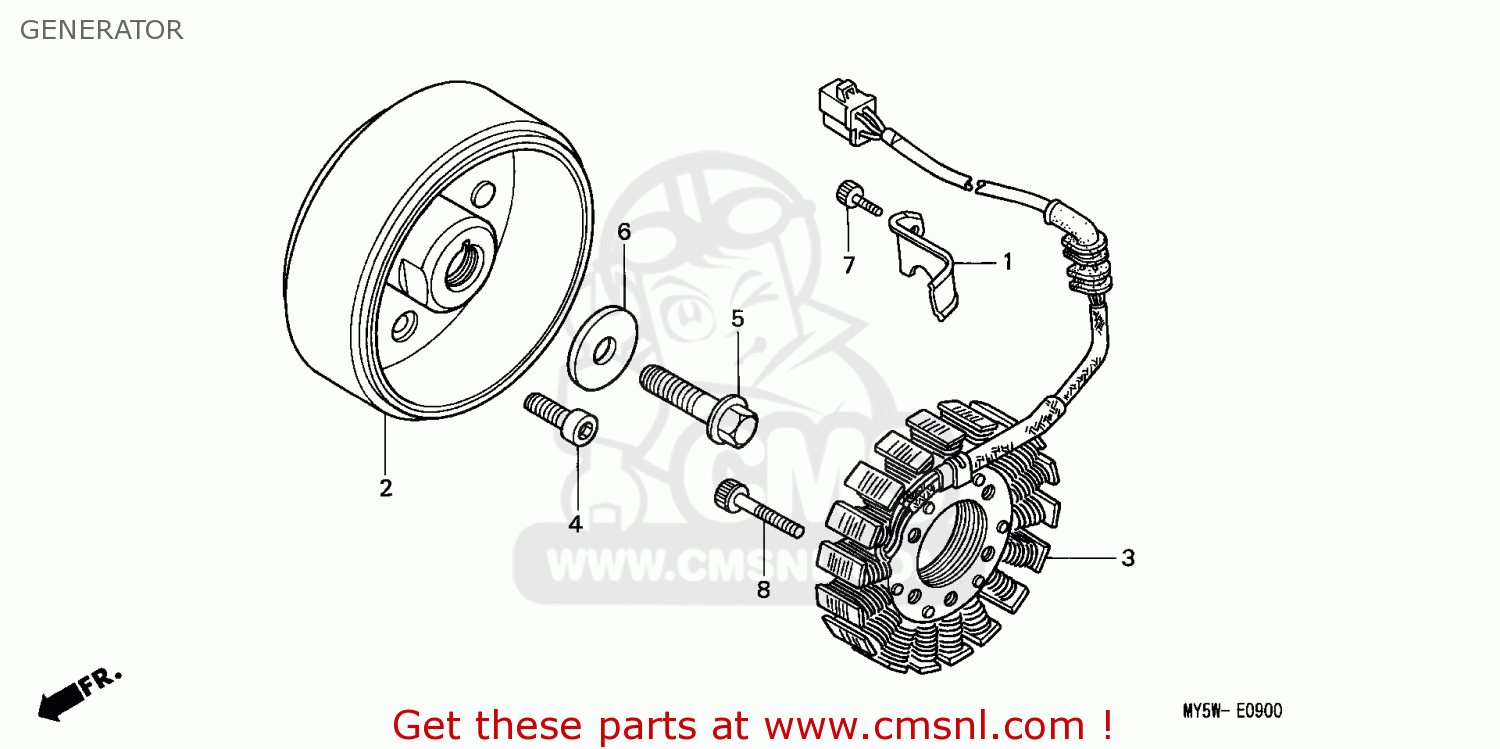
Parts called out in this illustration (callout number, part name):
1	CLAMP,ACG CORD
2	FLYWHEEL COMP.
3	STATOR COMP.
4	BOLT,SOCKET 8X18
5	BOLT,FLANGE,10MM
6	WASHER,10X36X4.5
7	BOLT,SOCKET 6X12
8	BOLT SOCKET 6X28
